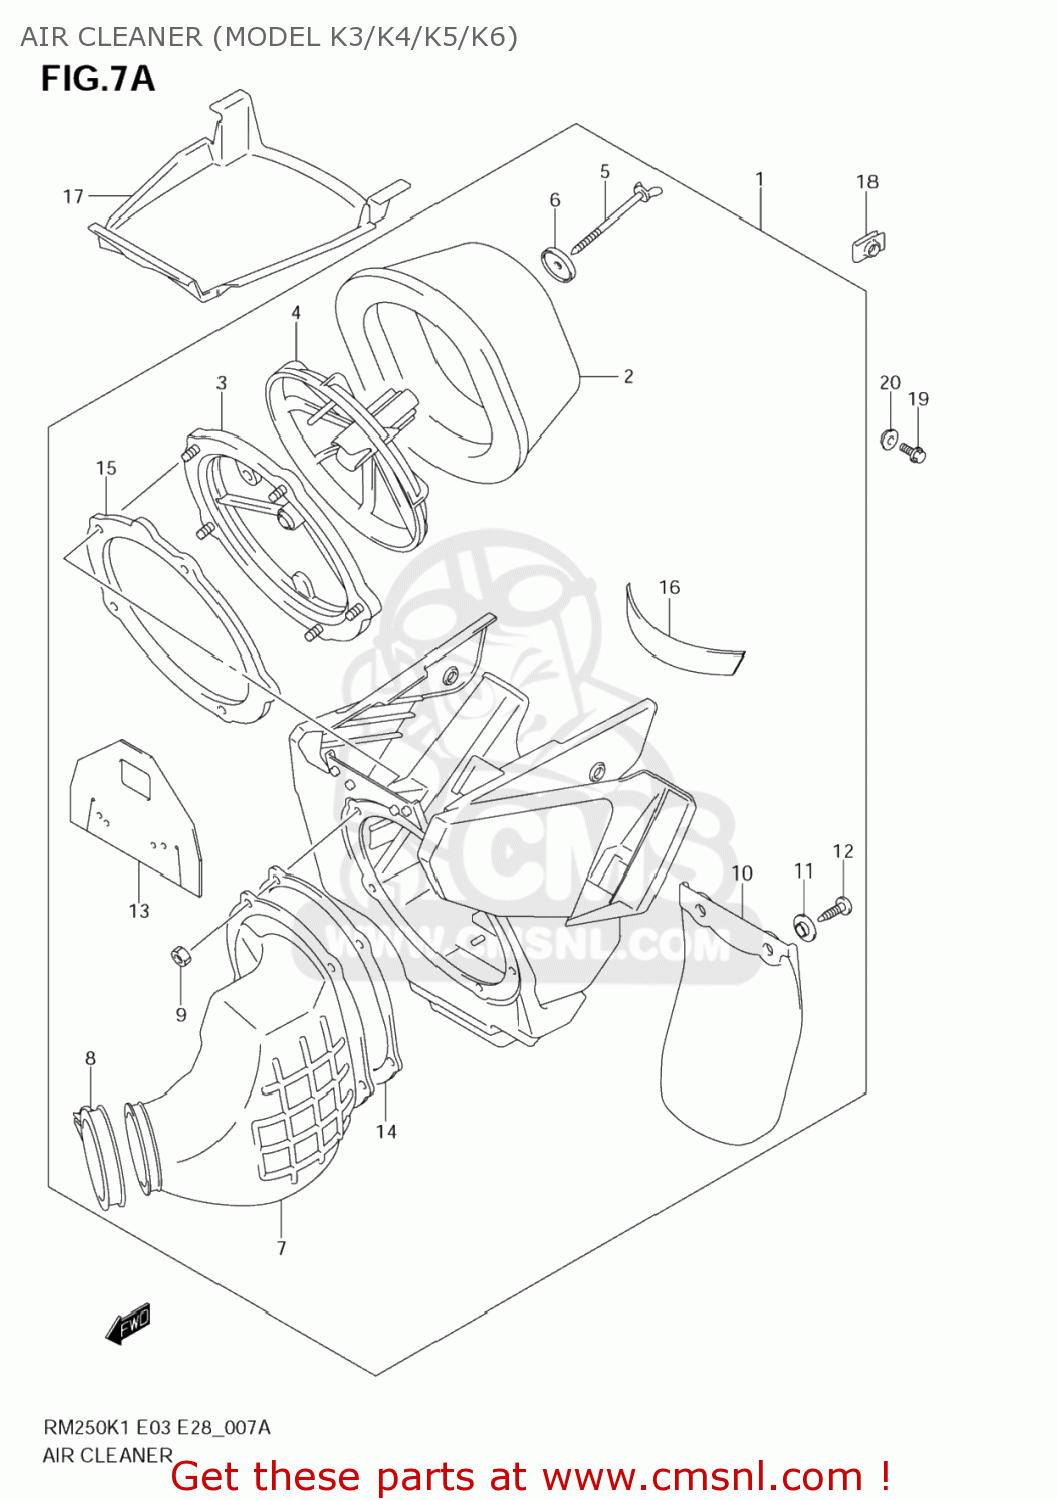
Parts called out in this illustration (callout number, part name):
1	CLEANER ASSY,AIR
2	FILTER ASSY
3	BASE,FILTER
4	HOLDER,FILTER
5	BOLT,WING
6	WASHER,AIR CLEANER
7	TUBE,OUTLET
8	CLAMP
9	NUT
10	MUDGUARD
11	COLLAR
12	SCREW
13	COVER,AIR CLEANER
14	PLATE
15	GASKET (NAS)
16	CUSHION,AIR CLEANER
17	CAP,AIR CLEANER
18	HOLDER,REAR BU
19	BOLT(6X10)
20	WASHER
